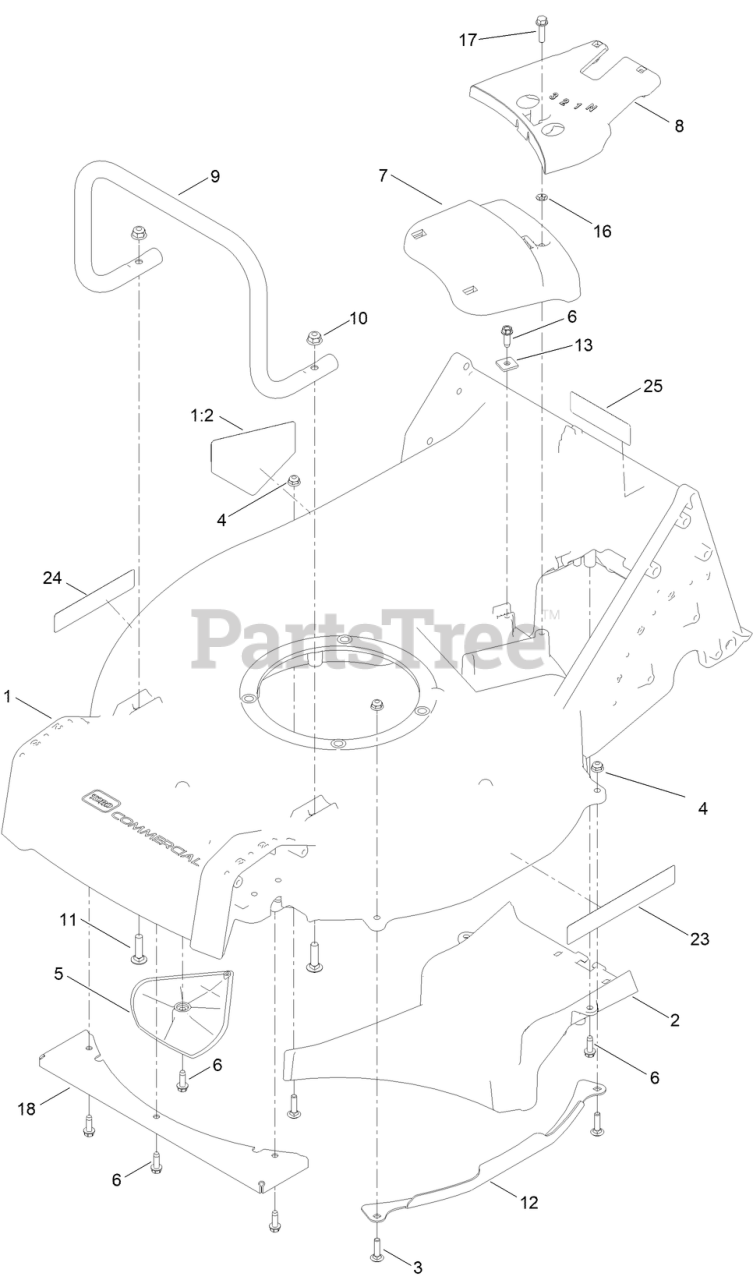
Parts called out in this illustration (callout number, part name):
1	HOUSING ASM
1:2	DECAL-DANGER
2	FLOOR-CHUTE
3	SCREW-CARR
4	NUT-HF
5	KICKER
6	SCREW-HWHTF
7	COVER-BELT, FRONT
8	COVER-BELT, REAR
9	GUARD-ENGINE
10	NUT-HF, NI
11	SCREW-CARR
12	GUARD-SIDE, DECK
13	CLAMP-CABLE
16	PUSHNUT-RETAINER, BOLT
17	SCREW-HWHTF
18	GUARD-TOE, FRONT
23	DECAL-RECYCLER
25	DECAL- EMISSIONS,PRE EU STAGE V, PRINTED
